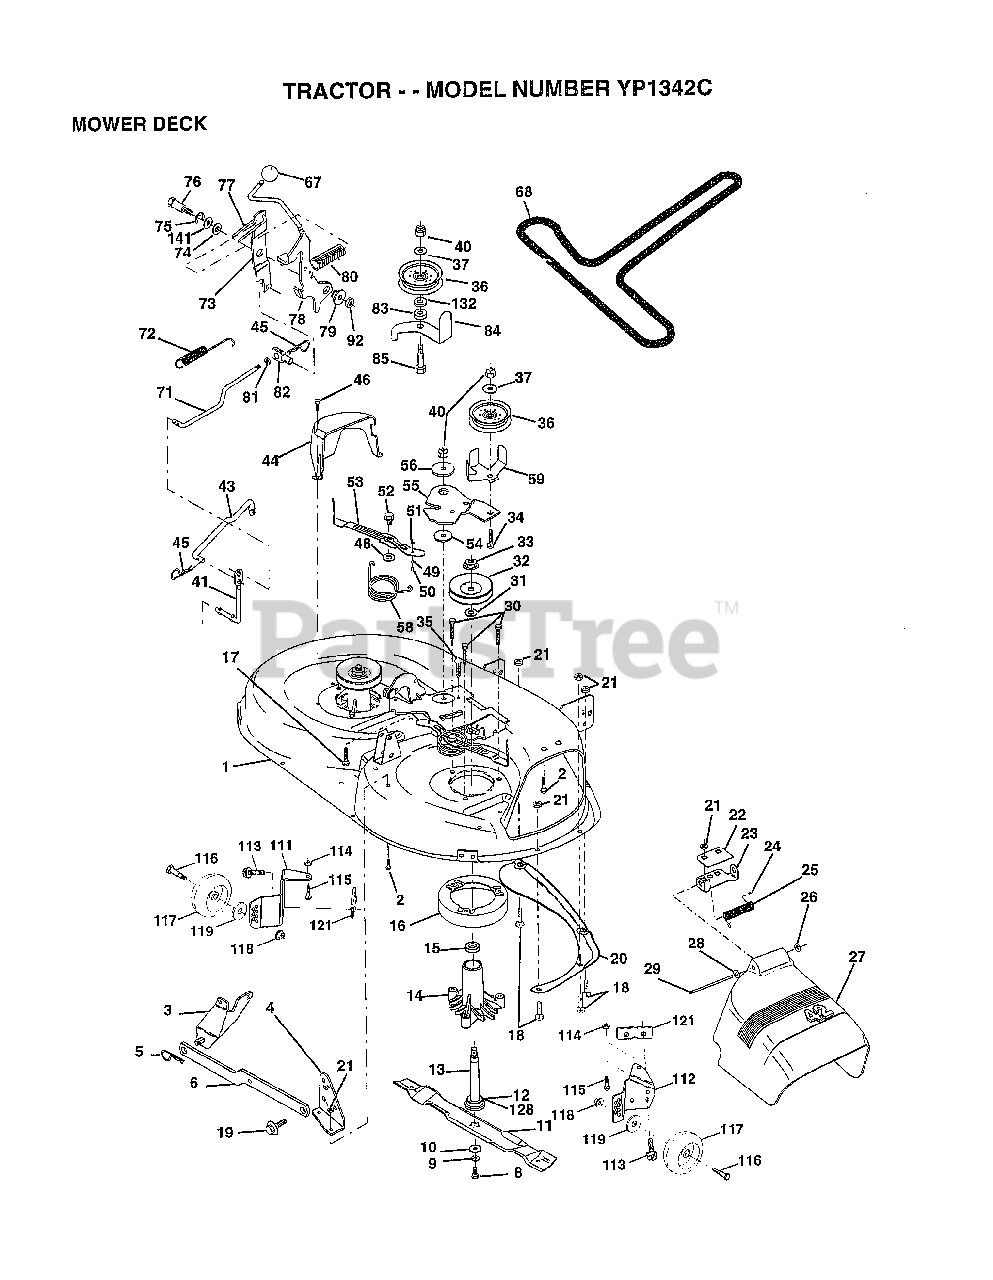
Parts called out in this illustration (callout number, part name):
1	DECK.WELD.42.
2	BOLT
3	BRKT ASM SWAY BAR
4	BRKT DECK SW BAR
5	SPRING TORSN BRAK
8	BLADE BOLT
10	WASHER.HARD.BLADE
11	"BLADE.42"" HIPERF"
12	BEARING.BALL
14	HSG ASM MANDREL
15	BEARING
16	STRIPPER RND MWR
17	BOLT RDHD 3/8-16
18	BOLT
19	BOLT SHD 5/16-18
20	BAFFLE VORTEX 42
22	STIFFENER BRKT
23	DEFLECTOR BRKT
25	SPRING TORSION
27	DEFLECTOR.SHIELD
28	WASHER
29	HINGE ROD
30	"SCREW-THD ROLL,WA"
31	WASHER
32	PULLEY.MANDREL.42
34	BOLT
35	XMAS TREE FASTNER
36	FLAT IDLER PULLEY
37	WASHER
41	PIVOT ROD
43	ROD CLUTCH W/NIBS
44	GUARD MAND LH BLK
46	SCREW.1/4-20X5/8
48	HARD SMALL WASHER
49	ROLLER ASM-CAM
50	SHOULDER BOLT
51	LOCKNUT
52	BOLT.SHLD.5/16-18
53	BRAKE PAD ARM ASM
54	HARDENED WASHER
55	ARM-IDLER
56	SPACER RETAINER
59	GUARD IDLER TUV
67	KNOB.RD.7/16-14
68	BELT.V.T-PATH
71	ROD CLUTCH 38/42
72	RETURN SPRING
73	CLUTCH ARM SECOND
74	WASHER
75	RING
76	SHOULDER BOLT
77	SPRING KEEPER
78	LEVER.ASM.CLUTCH
79	BUSHING
80	SPRING.CLUTCH.MWR
81	NUT
82	TRUNION ADJ
83	WASHER
84	"KEEPER-BELT,FIXED"
85	BOLT RDHD 3/8-16
92	NUT
111	BRACKET.GWHL.LH.
112	BRACKET.GWHL.RH.
113	SCREW
116	BOLT.SHOULDER
117	WHEEL GAGE DONUT
118	LOCKNUT
119	WASHER 3/8 X 7/8 X 14 GA
121	BRACKET.EXTRD.GWL
128	WASHER.FELT.
132	WASHER GT
141	WASHER .T
